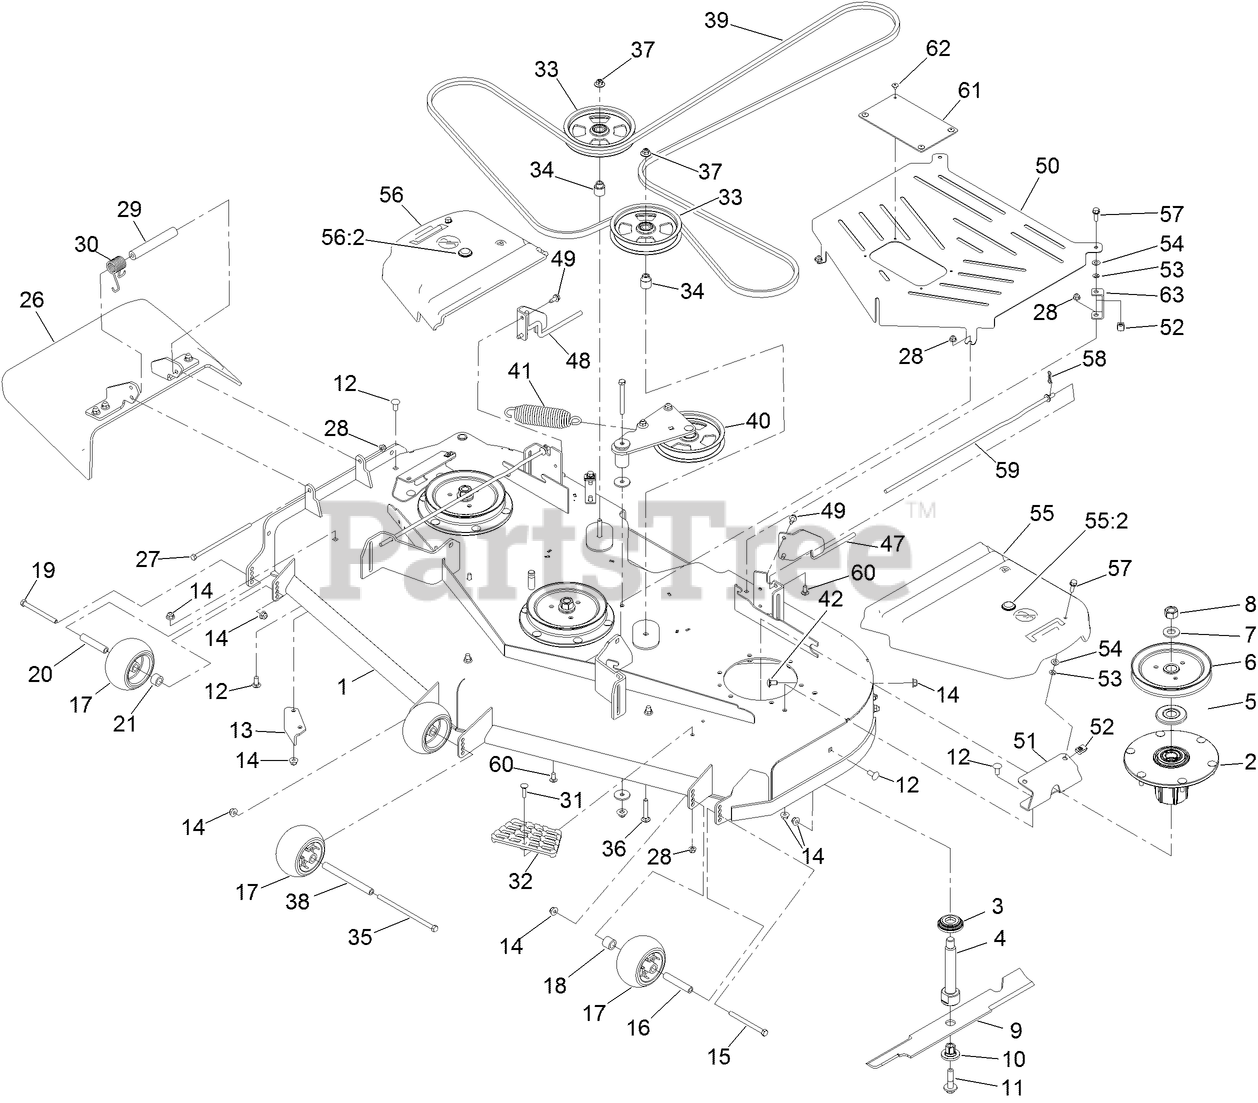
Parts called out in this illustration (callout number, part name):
1	DECK DECAL ASM
2	SPINDLE ASM
3	GUARD-BOTTOM
4	SHAFT-SPINDLE
5	GUARD-BEARING, TOP
6	SHEAVE-DRIVE, BLADE
7	WASHER
8	NUT-HEX
10	BUSHING-HEX
11	SCREW-SEMS
12	SCREW-CARR
13	BAFFLE-DISCHARGE
14	NUT-HF, NI
15	SCREW-HH
16	TUBE-SPANNER
17	ROLLER-SCALP, ANTI
18	TUBE-SPACER
19	SCREW-HH
20	TUBE-SHAFTING
21	TUBE-SPACER
26	RUBBER DEFLECTOR ASM
27	SCREW-HH
28	NUT-HF, NI
29	SPACER
30	SPRING-TORSION
31	SCREW-CARR
32	STEP-DECK
33	PULLEY-IDLER, FLAT
34	BUSHING, IDLER
35	SCREW-HH
36	SCREW-CARR
37	NUT-FLANGE, NI
38	SPACER-WHEEL
39	BELT-V
40	IDLER ARM ASM
41	SPRING-EXTENSION
42	SCREW-CARR
47	SUPPORT-LOWER LH
48	SUPPORT-LOWER RH
49	SCREW-HWHTF
50	GUARD-CENTER BELT 60
51	BRACKET-COVER, BELT
52	NUT-U
53	NUT-PUSH
54	WASHER-THRUST
55	LH BELT COVER ASM
55:2	PLUG-PLASTIC
56	RH BELT COVER ASM
56:2	PLUG-PLASTIC
57	SCREW-HHF
58	PIN-COTTER, LOCKING
59	ROD-SKIRT, LOWER
60	SCREW-CARR
61	SHIELD-RUBBER
62	RIVET-POP
63	BRACKET-GUARD
